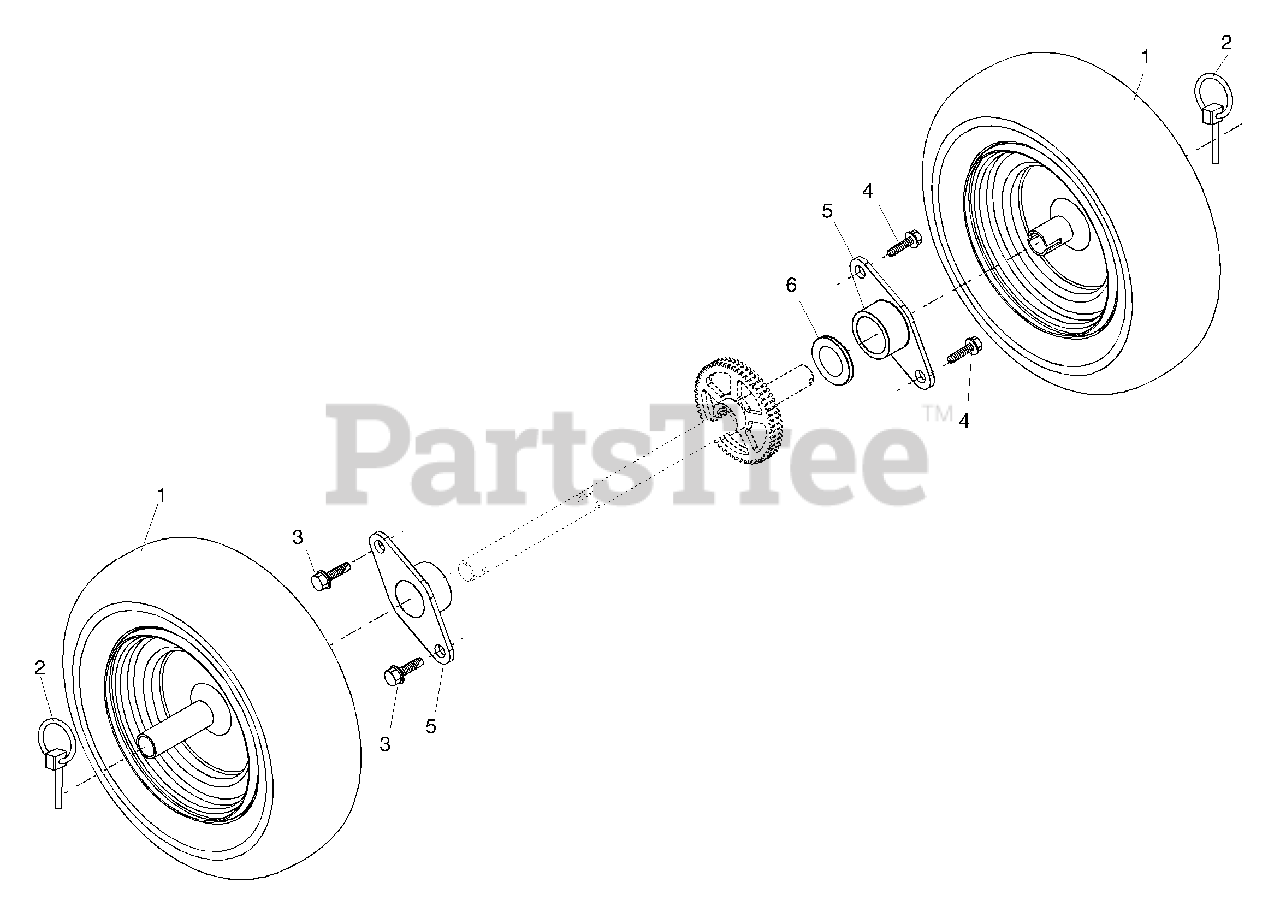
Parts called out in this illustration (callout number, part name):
1	Wheel Assembly (13")
2	Pin, Klik 1/4
3	Screw, Hex Head 5/16-18 x 3/4
4	Screw, Hex Head 5/16-18 x 1/2
5	Bearing, Axle
6	Washer, Thrust (1")
